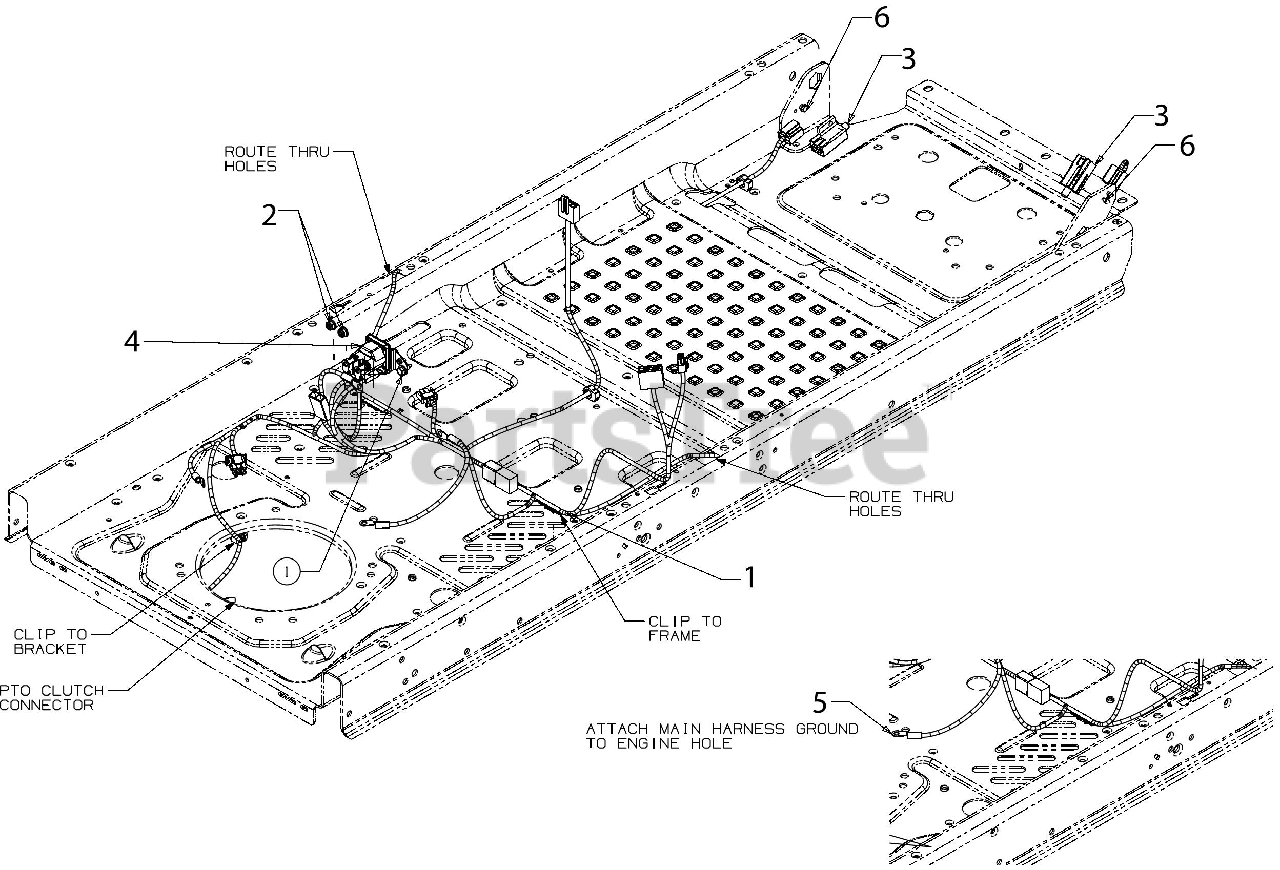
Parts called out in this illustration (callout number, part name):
1	SCREW 1/4-20X.625
2	FLANGE LOCK NUT
3	INTERLOCK SWITCH (NO/NC)
4	SOLENOID-12V 100A
5	MAIN HARNESS (E-PTO/PBS/RMC)
6	SHOULDER SCREW
